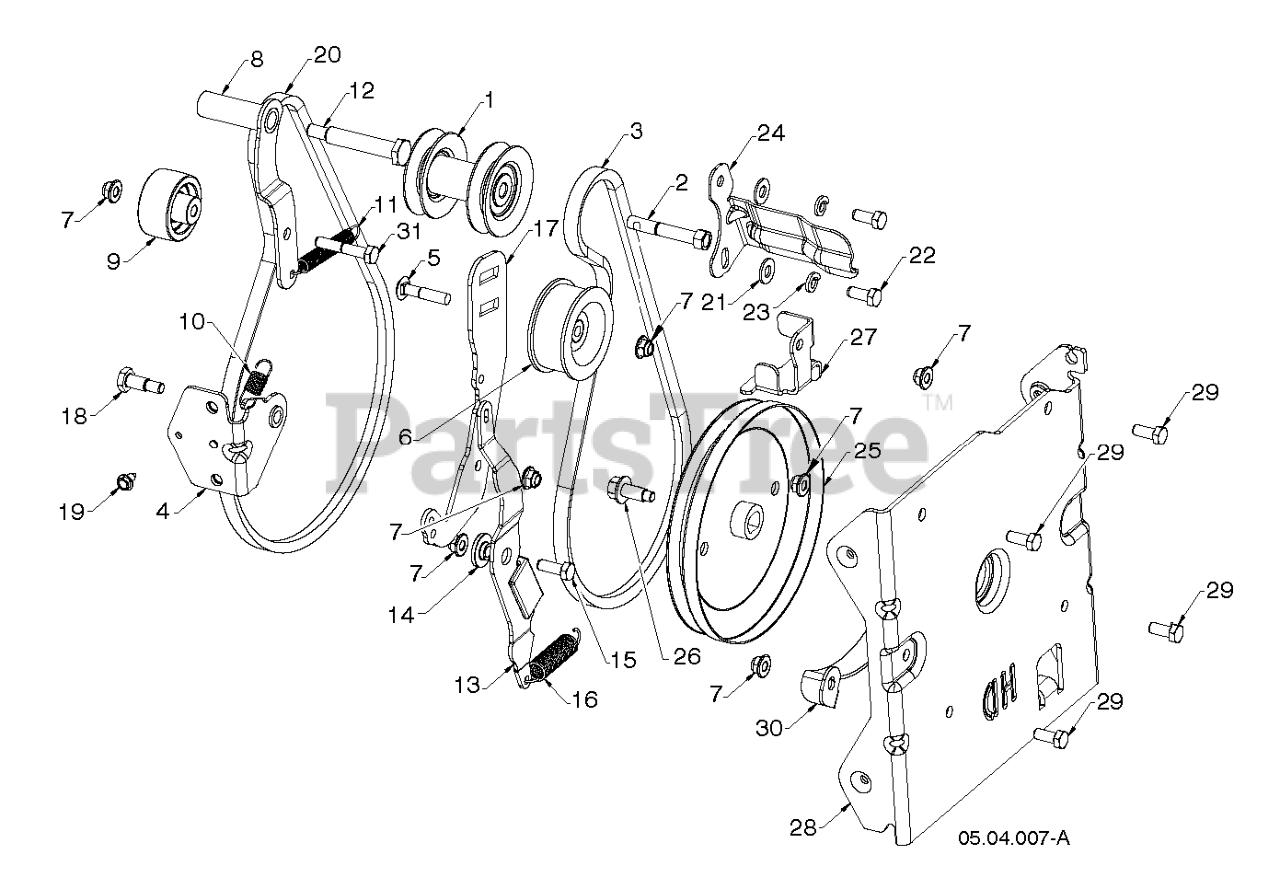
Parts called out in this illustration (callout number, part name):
1	PULLEY.ASM.IMPELLER/DRIVE
2	PULLEY.IDLER.FLNGLESS.W/SPACER
3	LOW CRANK IMPELLER BELT
4	BRACKET WELDMENT, IDLER ARM ZI
5	BOLT 5/16-18 CARRIAGE 1.5L
6	WASHER 11/32 X 11/16 X 14 GA T
7	NUTNYLOK.FLRANGE.5/16-18
8	ARM IDLER DRIVE WELDMENT_HOT
9	PULLEY.IDLER.FLANG.2.O/SPACER
10	SPRING IDLER RETURN
11	SPRING RETURN IDLER ARM
12	BOLT 5/16-24X2.25 HEX HEAD SHO
13	ARM IMPELLER BRAKE
14	BUSHING.BRAKE.ARM
15	BOLT HEXAGON BOLT 5/16-18 X 7/
16	SPRING EXTENSION - BRAKE
17	ARM IDLER BLACK ZINC
18	SCREW HEX HEAD SHOULDER
20	BELT.DRIVE.SNOW.DUAL
21	WASHER M
22	SCREW 5/16-24 X .75 GR5
23	WASHER SPRING LOCK WASHER WITH
24	BELT KEEPER BRACKET
25	PULLEY IMPELLER DD 4L HD
26	SCREW HEXAGON HEAD FLANGE 3/8-
27	GUIDE.LOWER.AUGER.BELT.479
28	BRACKET AUGER HOUSING INTERFAC
29	BOLT.FIN.HEX.5/16-18X3/4
30	BRACKET.BELT.KEEPER.LOWER.BLAC
31	BOLT, HEX 5/16-18X1-3/4
